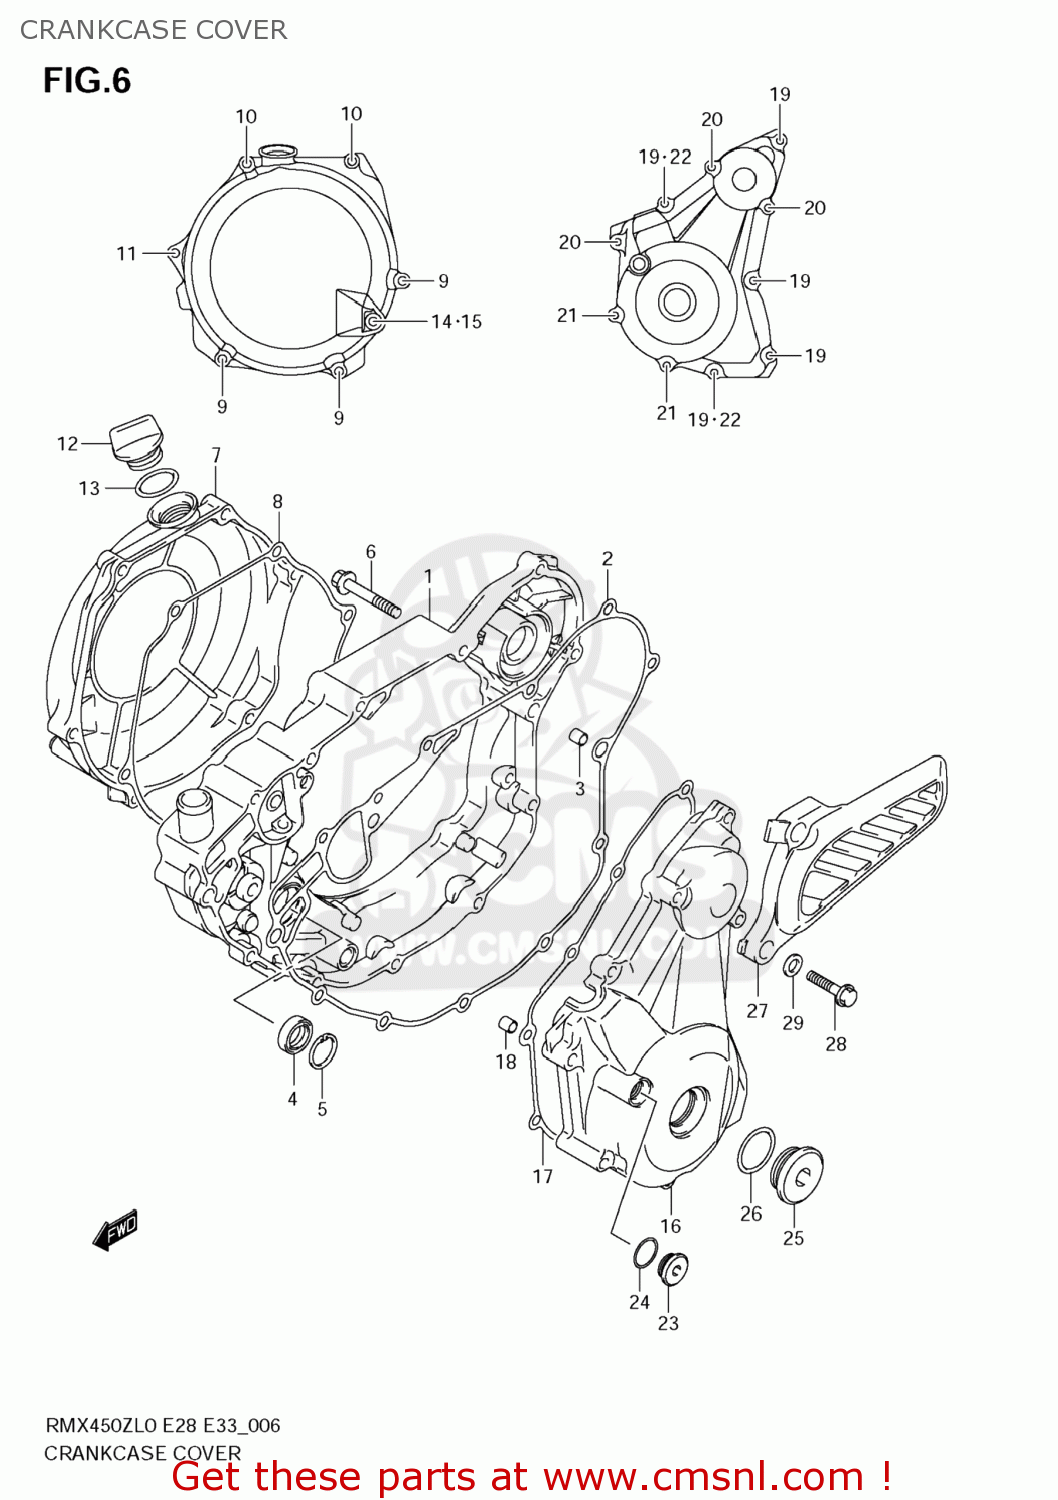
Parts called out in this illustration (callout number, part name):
1	COVER,CLUTCH
2	GASKET,CLUTCH COVER (NAS)
3	PIN
4	SEAL,OIL(12X22X6)
5	CIRCLIP
6	BOLT
7	COVER,CLUTCH OUTER
8	GASKET,CLUTCH COVER OUTER (NAS)
9	BOLT
10	BOLT
11	BOLT
12	PLUG
13	O RING(D:3.1,ID:16.8)
14	SCREW(6X10)
15	GASKET(6.2X11X1).2 (NAS)
16	COVER,MAGNETO
17	GASKET,MAGNETO COVER (NAS)
18	PIN
19	BOLT
20	BOLT
21	BOLT
22	GASKET(5.8X13X1.2) (NAS)
23	PLUG(12X9)
24	O RING(D:1.9,ID:9.8)
25	PLUG(26X9)
26	O RING(D:3.1,ID:22.7)
27	COVER,ENGINE SPROCKET
28	BOLT(6X30)
29	WASHER
